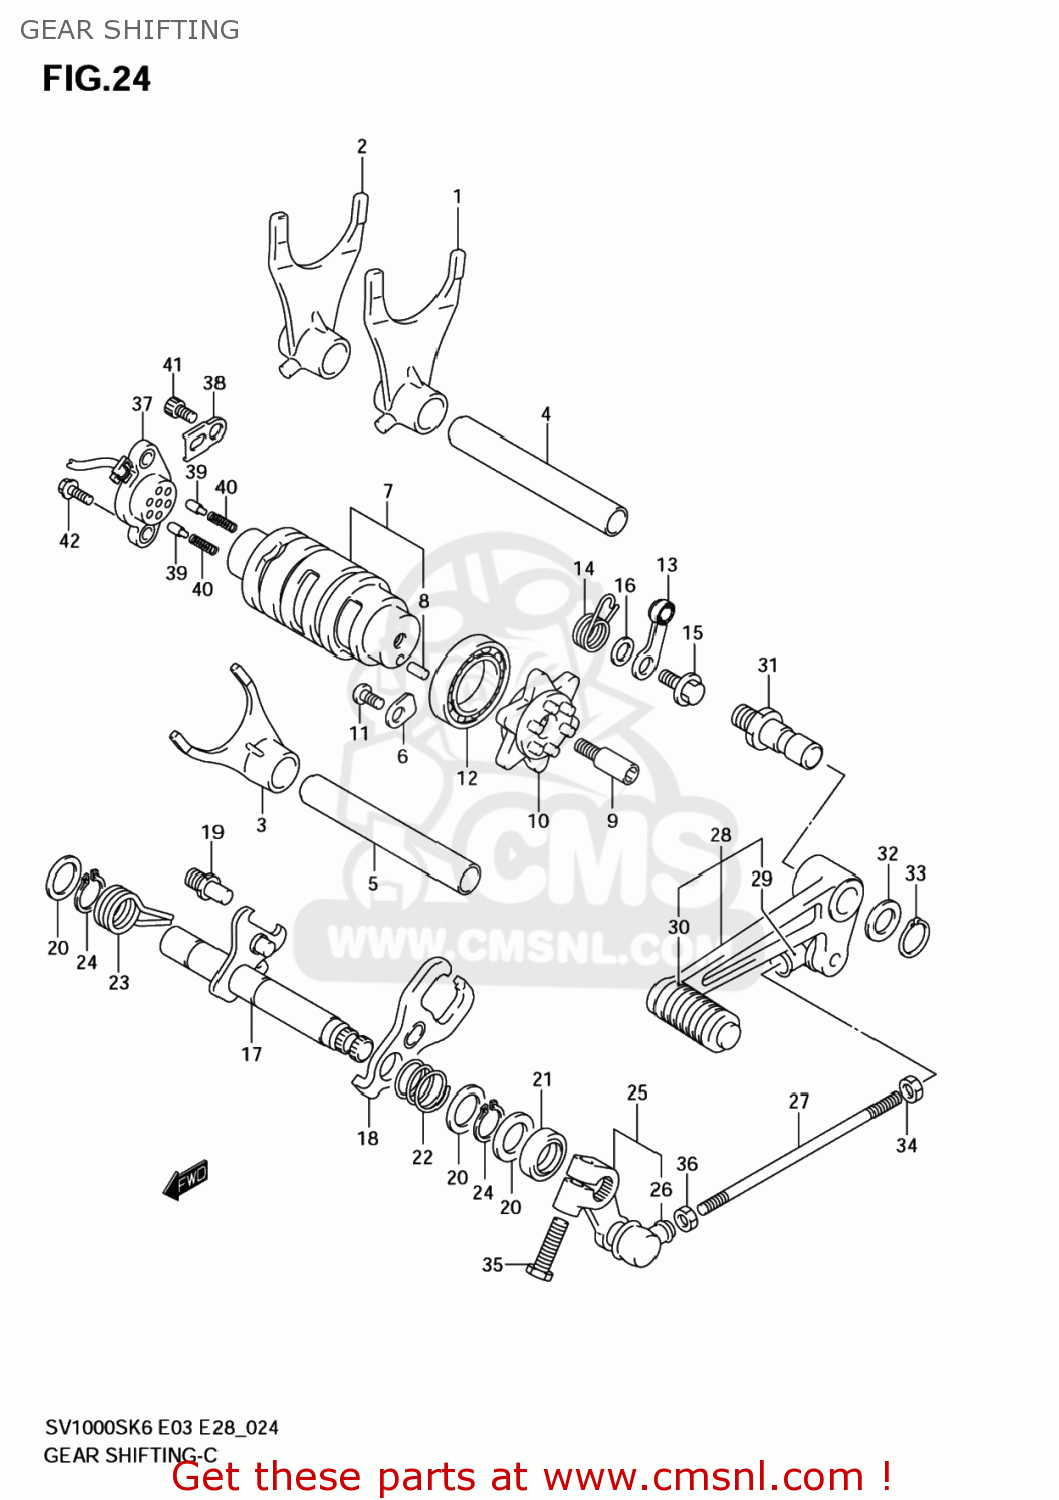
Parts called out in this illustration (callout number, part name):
1	FORK,GEAR SHIFT
2	FORK,GEAR SHIFT NO.1
3	FORK,GEAR SHIFT NO.3
4	SHAFT,GEAR SHIFT FORK
5	SHAFT,GEAR SHIFT FORK
6	RETAINER
7	CAM,GEAR SHIFT
8	PIN
9	PIN,SHIFT CAM DRIVEN GEAR
10	PLATE,GEAR SHIFT CAM
11	BOLT(6X12)
12	BEARING
13	STOPPER,SHIFT CAM
14	SPRING,GEAR SHIFT CAM STOPPER
15	BOLT(6X14.3)
16	WASHER
17	SHAFT,GEAR SHIFT
18	PLATE,GEAR SHIFT CAM DRIVE
19	STOPPER,GEAR SHIFT ARM
20	SHIM(14X22X1)
21	SEAL,OIL(14X22X6)
22	SPRING
23	SPRING
24	CIRCLIP
25	ARM,GEAR SHIFT LINK
26	COVER,DUST
27	ROD,GEAR SHAFT LINK
28	LEVER ASSY,GEAR SHIFT
29	COVER,DUST
30	RUBBER,GEAR SHIFT PEDAL
31	SHAFT,GEAR SHIFT LEVER
32	WASHER(12.5X20X1)
33	CIRCLIP,12 MM
34	NUT
35	BOLT
36	NUT
37	BASE ASSY,GEAR SHIFT TERMINAL
38	CLAMP,GENERATOR LEAD WIRE
39	PIN(5X15.5)
40	SPRING
41	BOLT
42	BOLT
